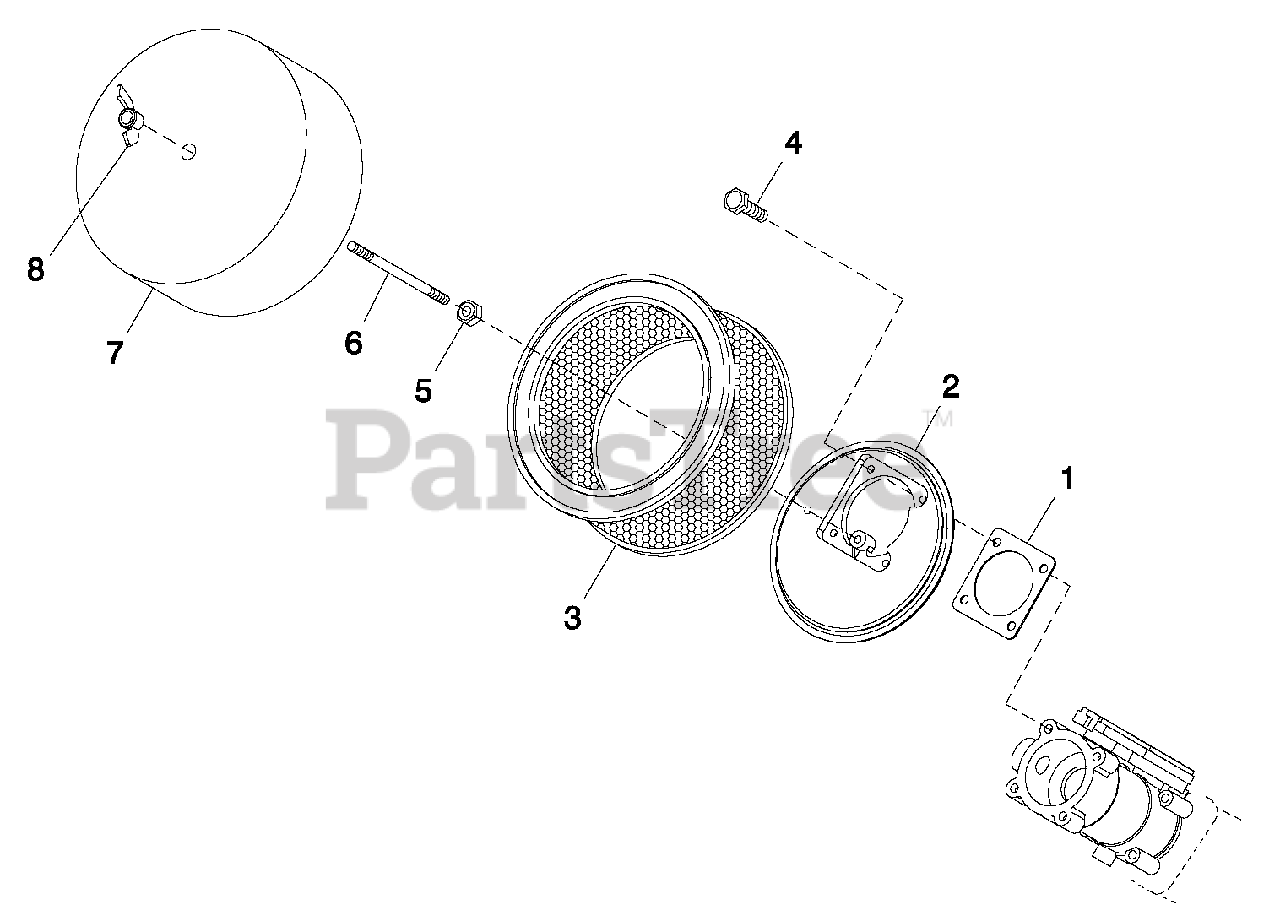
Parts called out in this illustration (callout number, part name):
1	GASKET BOSCH 32 & 40
2	ADAPTER CARBURETOR W/PVC CONN
3	ELE MENT AIR CLEANER
4	SCREW HHCM5-0.8X 16 G8.8
5	NUT HEX 1/4-20 STEEL
6	STUD TH 1/4-20 X 4-1/2 G2ZNC
7	PLATE, AIR CLEANER TOP 2.4L
8	NUT WING 1/4-20 NYLK
